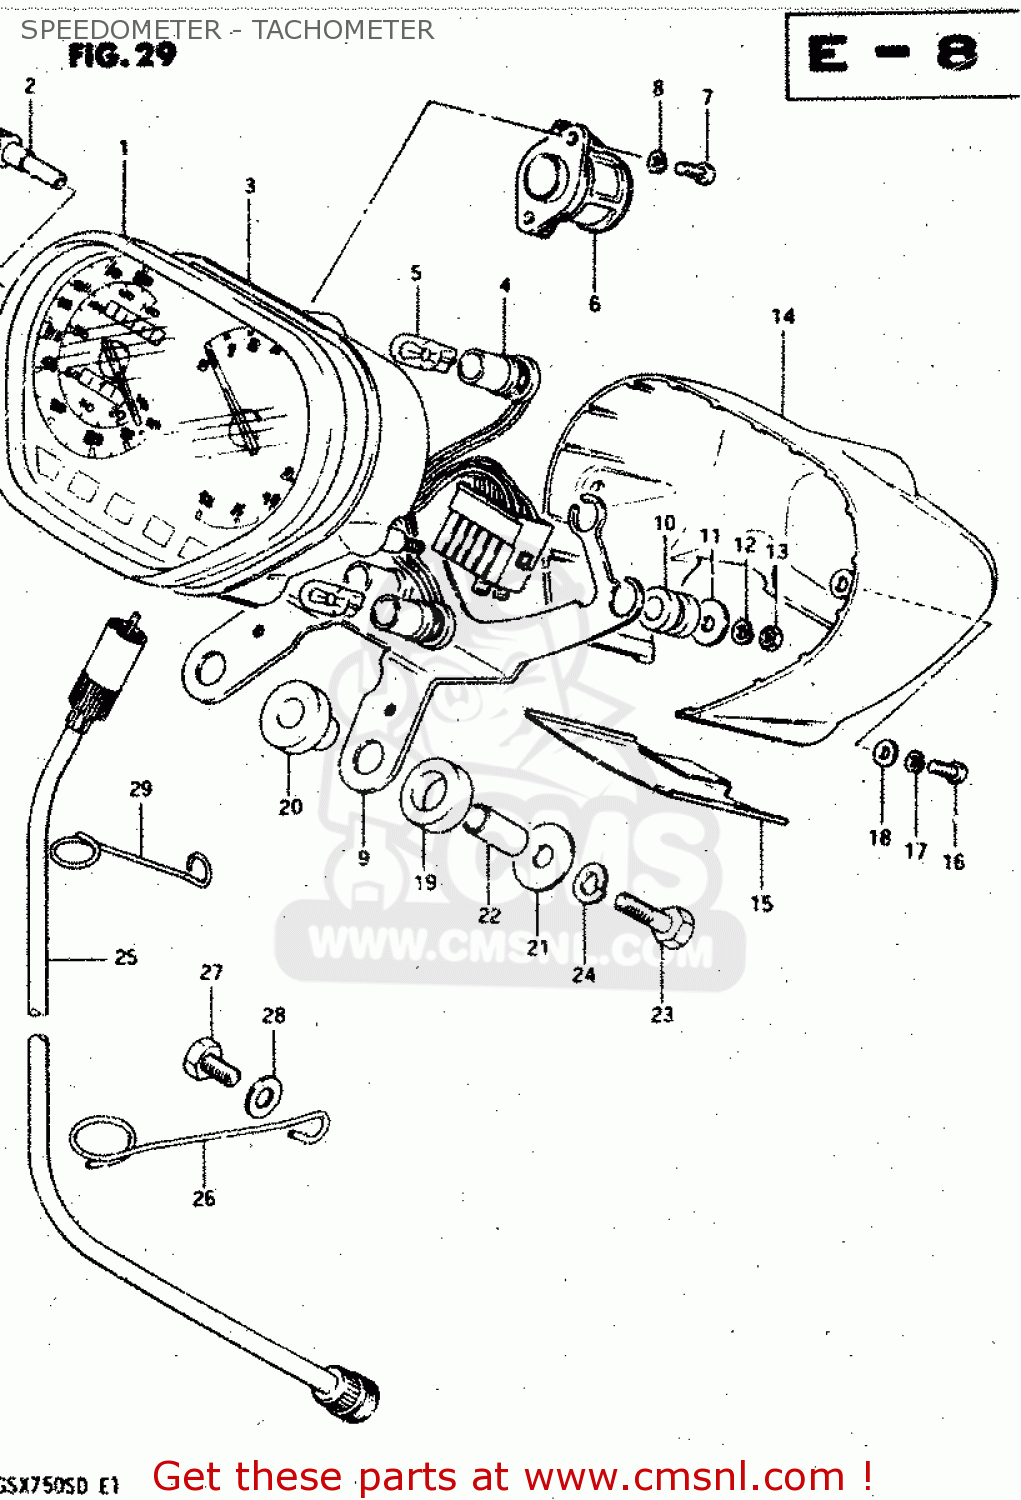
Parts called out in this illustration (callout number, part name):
1	SPEEDO & TACHOMETER
2	KNOB,TRIP METER
3	CUSHION
4	SOCKET
5	BULB(12V3.4W,T10,BF175-01450A)
6	GEAR BOX,SPEEDOMETER
7	SCREW 4X10
8	LOCK WASHER
9	BRACKET,METER
10	CUSHION
11	WASHER,COMBINATION METER
12	LOCK WASHER
13	NUT
14	COVER,LWR
15	PLATE,SPEEDOMETER
16	SCREW
17	LOCK WASHER
18	WASHER
19	CUSHION
20	CUSHION
21	WASHER (6.5X24X1.6)
22	SPACER (6.1X8X15.5)
23	BOLT
24	LOCK WASHER
25	CABLE ASSEMBLY,SPEEDOMETER
26	CLAMP,SPEEDOMETER CABLE
27	BOLT, UPPER
28	WASHER
29	GUIDE,SPEEDOMETER CABLE UPR
